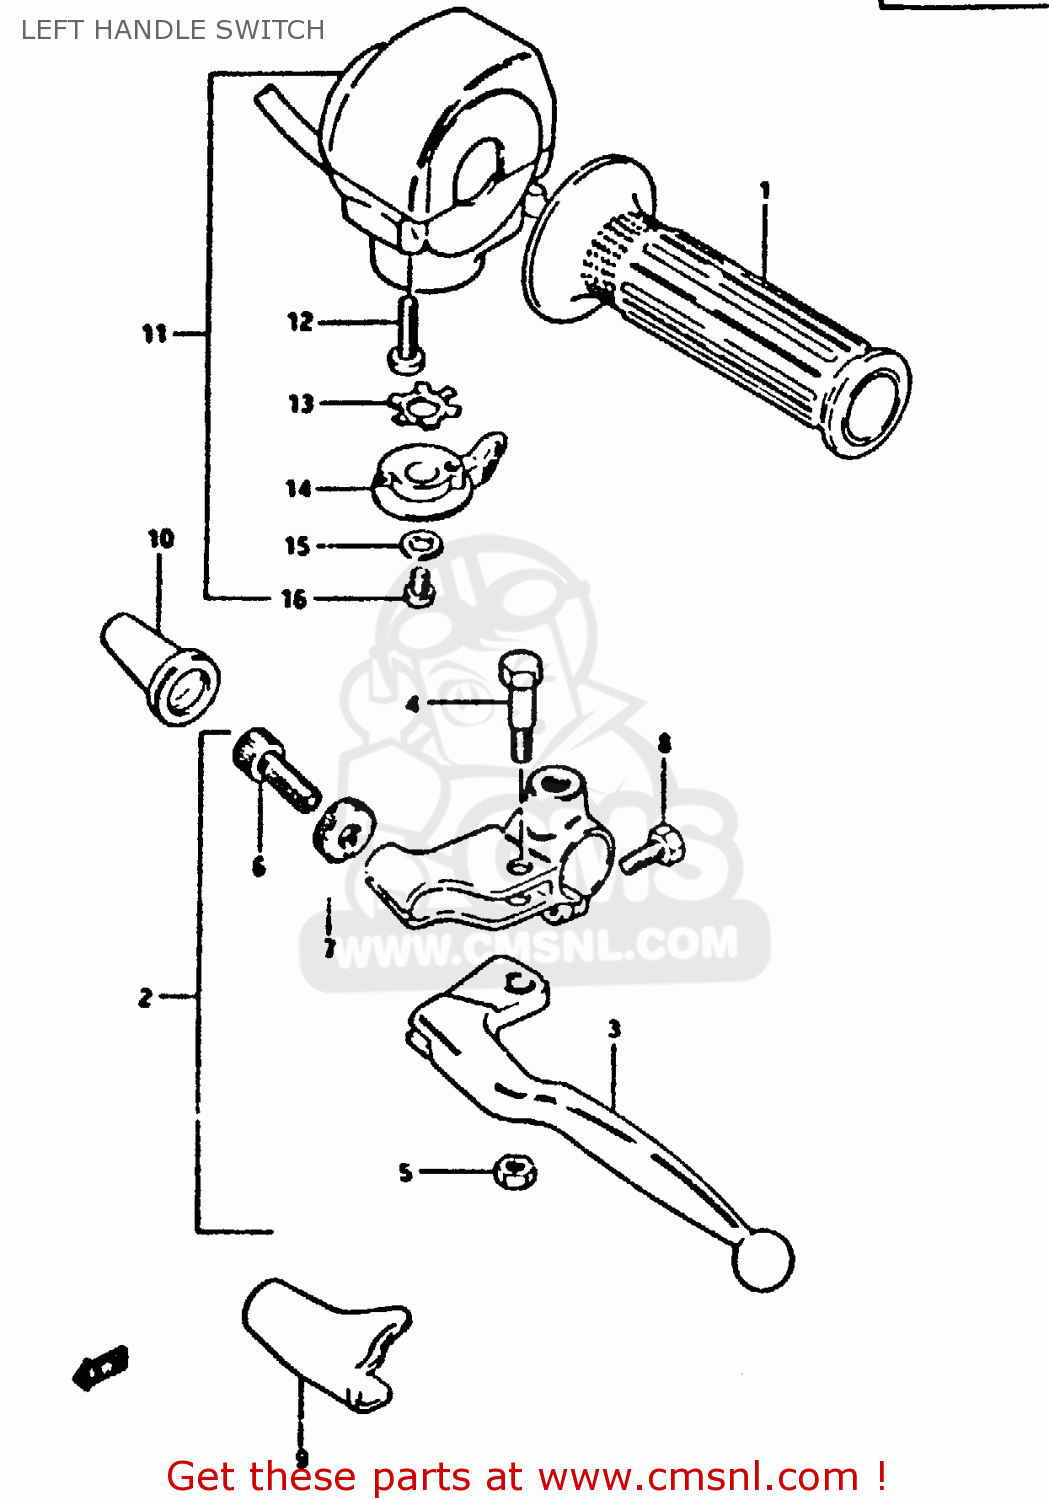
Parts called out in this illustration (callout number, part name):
1	GRIP,L
2	LEVER ASSY, CLUTCH
3	LEVER,CLUTCH
4	BOLT,LEVER PIVOT
5	NUT 6MM
6	ADJUSTER,CABLE
7	NUT,CABLE ADJUSTER
8	BOLT,CLUTCH LEVER HOLDER
9	COVER,CLUTCH LEVER
10	BOOT,CLUTCH CABLE
11	SWITCH ASSY, HANDLE LH
12	SCREW
13	WASHER
14	LEVER,CHOKE
15	WASHER 6MM
16	SCREW
